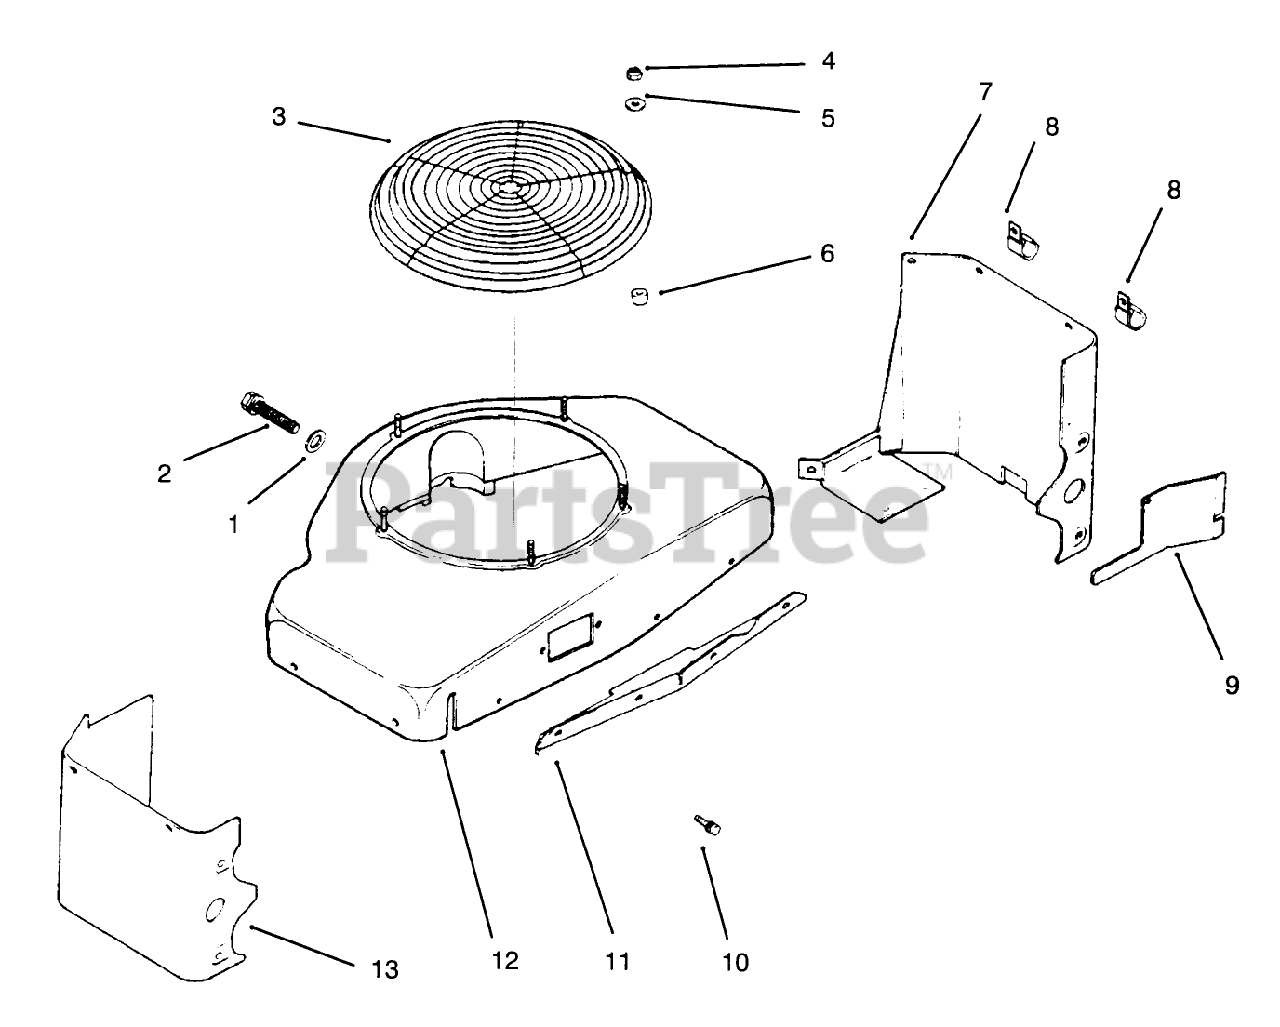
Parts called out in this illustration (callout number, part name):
2	Screw-Self Tap
3	GuARd-Grass Screen
4	Locknut
7	Baffle-Cylinder Head
8	Clip-Cable (Only On: 72103)
9	Baffle-Cylinder Head
10	Screw
11	Support-Upper Housing
12	Kit-Blower Housing
13	Baffle-Cylinder Head
